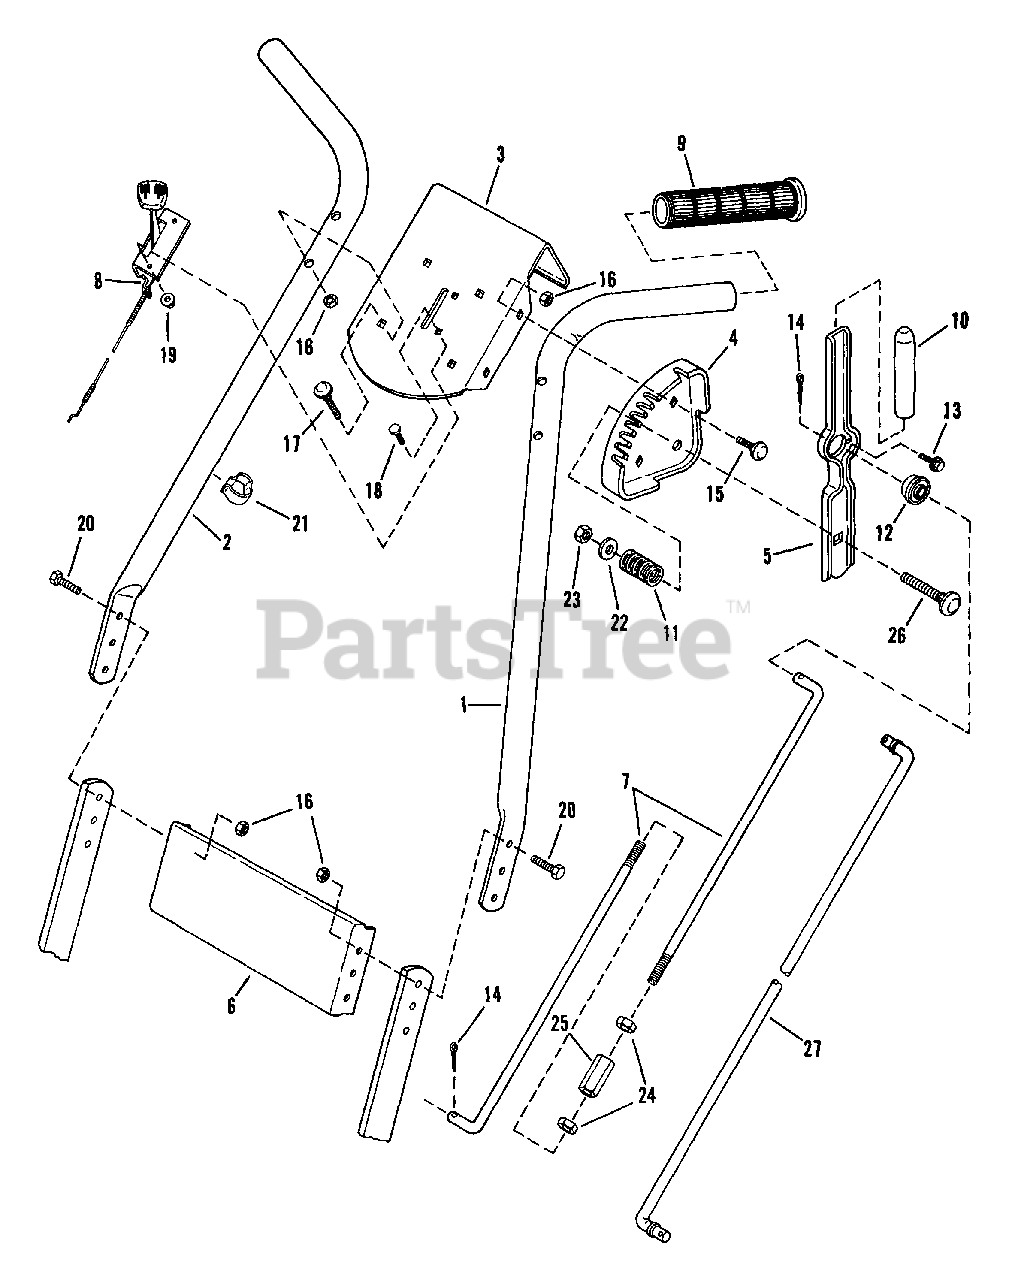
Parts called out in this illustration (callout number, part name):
1	HANDLE, Left
2	HANDLE, Right
3	PANEL, Control
4	QUADRANT, Depth Control
5	HANDLE, Depth Control
6	PANEL, Name Plate
7	ROD, Depth Control
8	THROTTLE, Control
9	GRIP, Handle
10	GRIP, Lift
11	SPRING, Depth Lever
12	BEARING
13	SCREW, #10-32 x 1/4" Self-Tapping
14	PIN, 1/8 x 1" Cotter
15	BOLT, 1/4-20 x 5/8" Short Neck Carriage
16	NUT, 1/4-20 Hex Center Lock
17	BOLT, 1/4-20 x 1-1/4" Carriage (GR.2)
18	BOLT, #10-24 x 1/2" Carriage
19	NUT, #10-24 Hex Flange Lock
20	SCREW, 1/4-20 x 7/8" Hex Cap
21	CLIP, Cable
22	WASHER, 3/8" Flat
23	NUT, 3/8-16 Hex Lock
24	NUT, 3/8-16 Hex
25	CONNECTOR
26	BOLT, 3/8-16 x 2" Carriage
27	ROD, Depth Control
